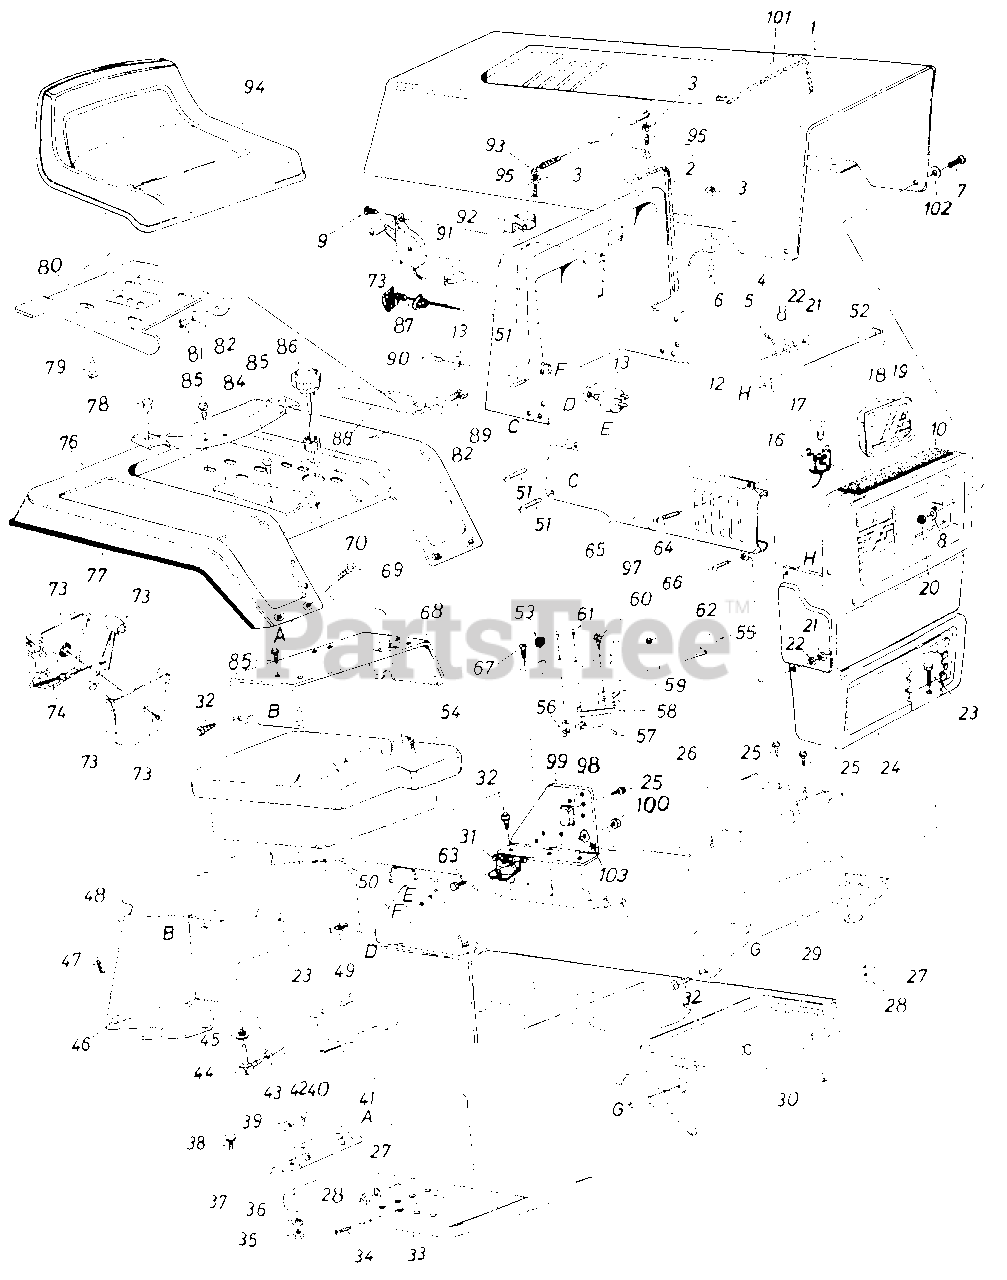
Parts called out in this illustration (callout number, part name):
1	Hood
2	Trim Strip-27" Lg.
3	Hex Sems Nut #10-24 Thd.
4	Fl-Wash. .20" I.D. x.41"
5	Hood Stop
6	Truss Hd. Mach. Scr. #10-24 x.50" Lg.
7	Shld. Bolt .375 Dia. x .125
8	Fl-Wash. 1/4" I.D.
9	Truss Mach. AB-Tap Scr. #10 x .50" Lg.
10	Foam Strip 3/8" x 1" x 14"
12	Dash Ass'y.
13	Ignition Switch
16	Socket
17	Lamp
18	Headlight Housing
19	Lens
20	L-Nut 1/4-28 Thd.
21	Hex Nut 1/4-20 Thd.
22	L-Wash. 1/4" I.D.
23	Hex Bolt 5/16-18 x .75" Lg.
24	Grille
25	Hex Wash. Hd. Scr. 1/4" x .50" Lg.
26	Battery Plate
27	L-Wash. 5/16" I.D.
28	Hex Nut 5/16-18 Thd.
29	Grille Mounting Bracket
30	Lower Frame Ass'y.
31	Solenoid
32	Hex Thd. Rolling Scr. 5/16-24 x .75" Lg.
33	Running Board-R.H.
34	Truss Mach. Scr. 5/16-18 x .75" Lg.
35	Hex Nut 5/16-18 Thd.
36	Bell-Wash. .34" I.D. x .87"
39	Hex Nut 1/4-20 Thd.
40	L-Wash. 1/4" I.D.
41	Running Board Rod
42	Fuel Line 40" Lg.
43	Hose Clamp 3/8"
44	90ø Nipple
45	Bushing
46	Hitch Rod
47	Internal Cotterpin
48	Hitch Plate
49	Speed Nut
50	Dash Support Brkt.-R.H.
51	Hex Wash. Hd. Tap Scr. 1/4 x.75" Lg.
52	Tie Strap
53	Plastic Bushing
54	Fuel Tank
55	Transmission Cover Ass'y.
56	Speed Nut #10-24 U-Type
57	Shift Lever Spring
58	Switch Spring
59	Insulator Plate
60	Hex Wash. Hd. AB-Tap Scr. #18 x .50
61	Truss Mach. Scr. #10 x .50" Lg.
62	Snap Bushing
63	Hex Bolt 1/4-20 x .50" Lg.
64	Truss Hd. Scr. 1/4-20 x .75" L.g*
66	Truss Mach. Scr. 1/4-20 x .50" Lg.
67	Truss Mach. "B" Tap Scr. #10 x .50" Lg.
68	Seat Mounting Channel
69	Carriage Bolt 1/4-20 x .50" Lg.*
70	Seat Bracket-R.H.
73	Throttle Control Box Ass'y.
74	Throttle Control Wire
78	Grommet
79	Hex Wash. Hd. AB-Tap Scr. 3/8 x .75" Lg.
80	Seat Pivot Bracket
81	Hex Cent. L-Nut 5/16-18 Thd.
82	Belleville Wash. .34" I.D. x .88" O.D.
84	Seat Spring
85	Hex Wash. Hd. Self-Tap Scr. 5/16-18 x .50" Lg.
86	Gas Cap w/Gauge
87	Choke Control Comp.
88	Seat Bracket-L.H.
89	Hex Bolt 5/16-18 x .75" Lg.
90	Ignition Key
91	Light Switch
92	Ammeter
93	Hood Spring
94	Seat Ass'y.
95	Hex Screw #10-24 x 1.0" Lg.
97	Rubber Strip 1/2" Sq. x 21/2" Lg.
98	Circuit Breaker
99	Dash Support Brkt.-L.H.
100	Hex Sems Nut 1/4-20 Thd.
101	PVC Foam Strip
102	Washer .34" I.D. x .62"
103	External L-Wash. 1/4" I.D.
